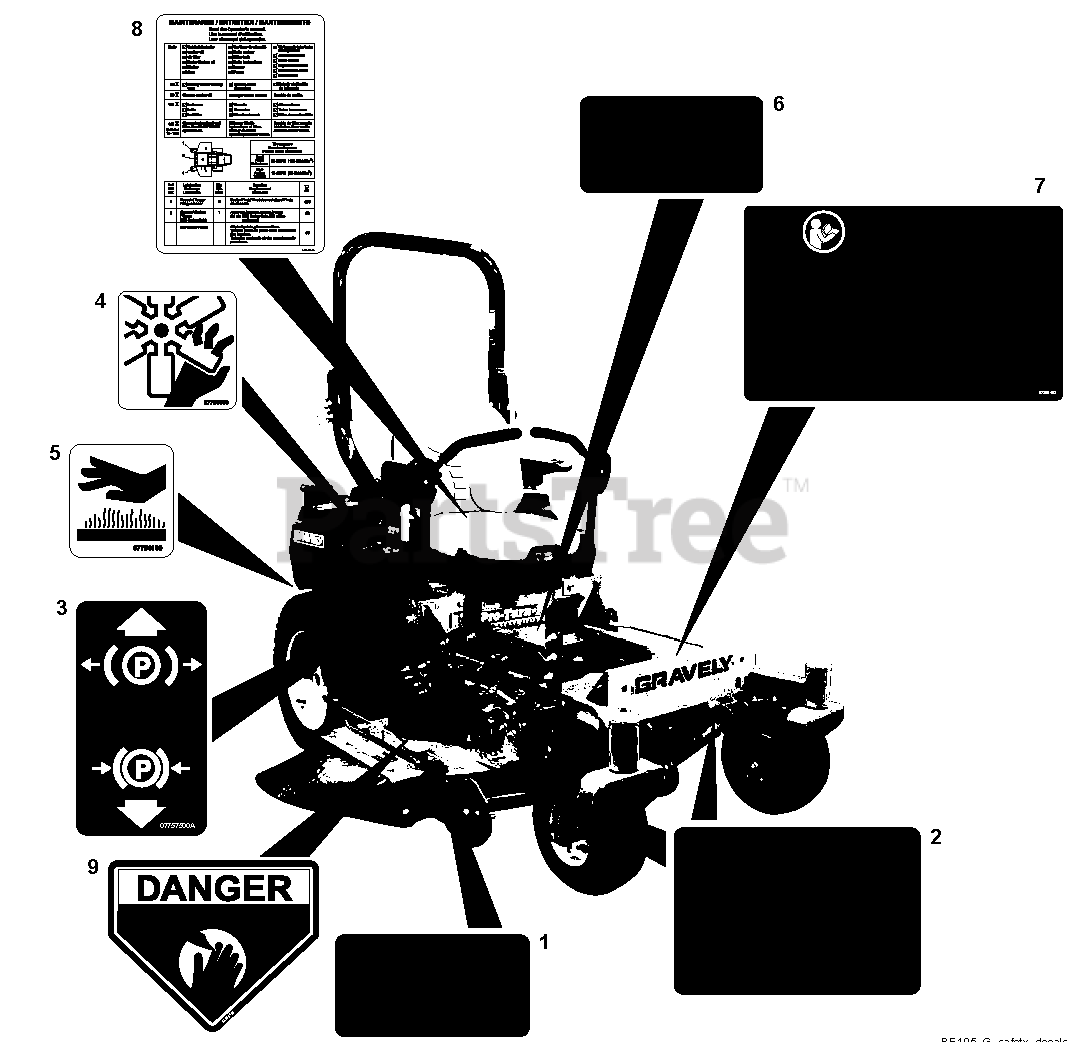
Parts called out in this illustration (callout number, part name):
1	Decal, Safety Deck Guarding
2	Decal, Safety Mower Deck
3	Decal, Parking Brake Lever
4	Decal, Danger Fan
5	Decal, Hot Surface
6	Decal, Safety Guarding
7	Decal, Main Safety Commercial
8	Decal, Maintenance Instructions
9	Decal, Danger
